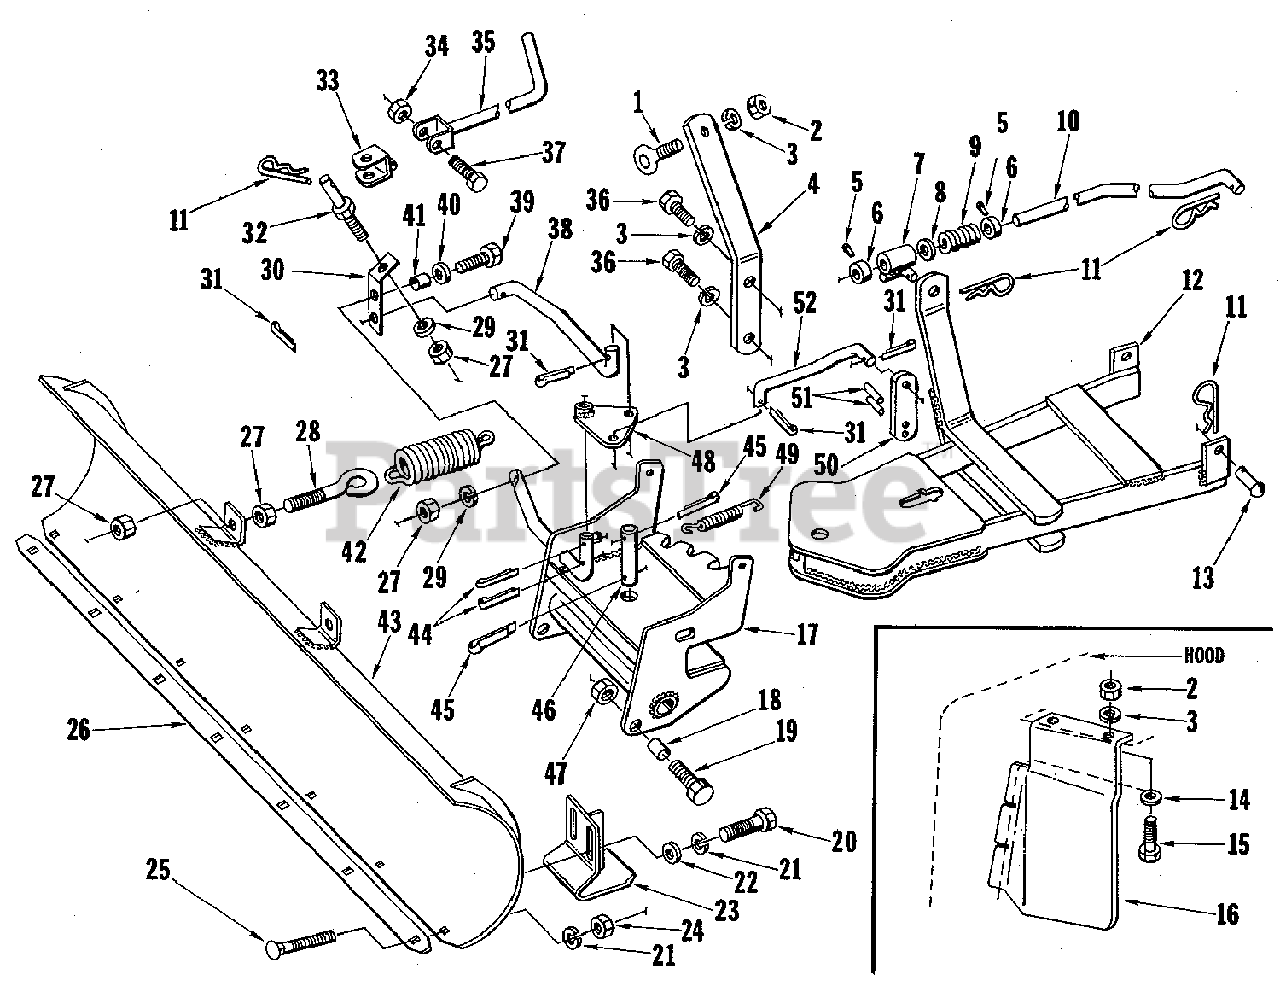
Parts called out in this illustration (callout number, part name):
2	NUT, Hex, 1/4-20
3	WASHER, Lock, 1/4
4	BRACKET, Handle Support
5	SCREW, Set, 5/16-18 x 3/8
7	GUIDE ASSEMBLY, Rod
8	WASHER, Flat, 17/32 x 1-1/4
10	ROD, Front Lift
11	PIN, Quick, 1/8
12	BAR ASSEMBLY, Push
14	WASHER, Flat, 1/4
15	SCREW, Cap, 1/4-20 x 1/2
16	DEFLECTOR, Snow
17	FRAME ASSEMBLY, Pivot
19	SCREW, Cap, 1/2-13 x 1-1/2
20	SCREW, Cap, 3/8-16 x 3/4
21	WASHER, Lock, 3/8
22	WASHER, Flat, 3/8
23	SHOE ASSEMBLY
24	NUT, Hex, 3/8-16
25	BOLT, Carriage, 3/8-16 x 1
27	NUT, Hex, 5/16-18
29	WASHER, Lock, 5/16
31	PIN, Cotter, 3/32 x 3/4
33	FORK ASSEMBLY
34	NUT, Hex Lock, 5/16-18
35	ROD ASSEMBLY, Control
36	SCREW, Cap, 1/4-20 x 5/8
37	SCREW, Cap, 5/16-18 x 1-1/2
39	SCREW, Cap, 5/16-18 x 1
40	WASHER, Flat, 5/16
43	BLADE ASSEMBLY, 46"
44	PIN, Cotter, 1/8 x 1
45	PIN, Cotter, 3/16 x 1-1/4
47	NUT, Hex Lock, 1/2-13
48	PLATE ASSEMBLY, Pivot
49	SPRING, Latch
51	PIN, Roll, 7/32 x 1
